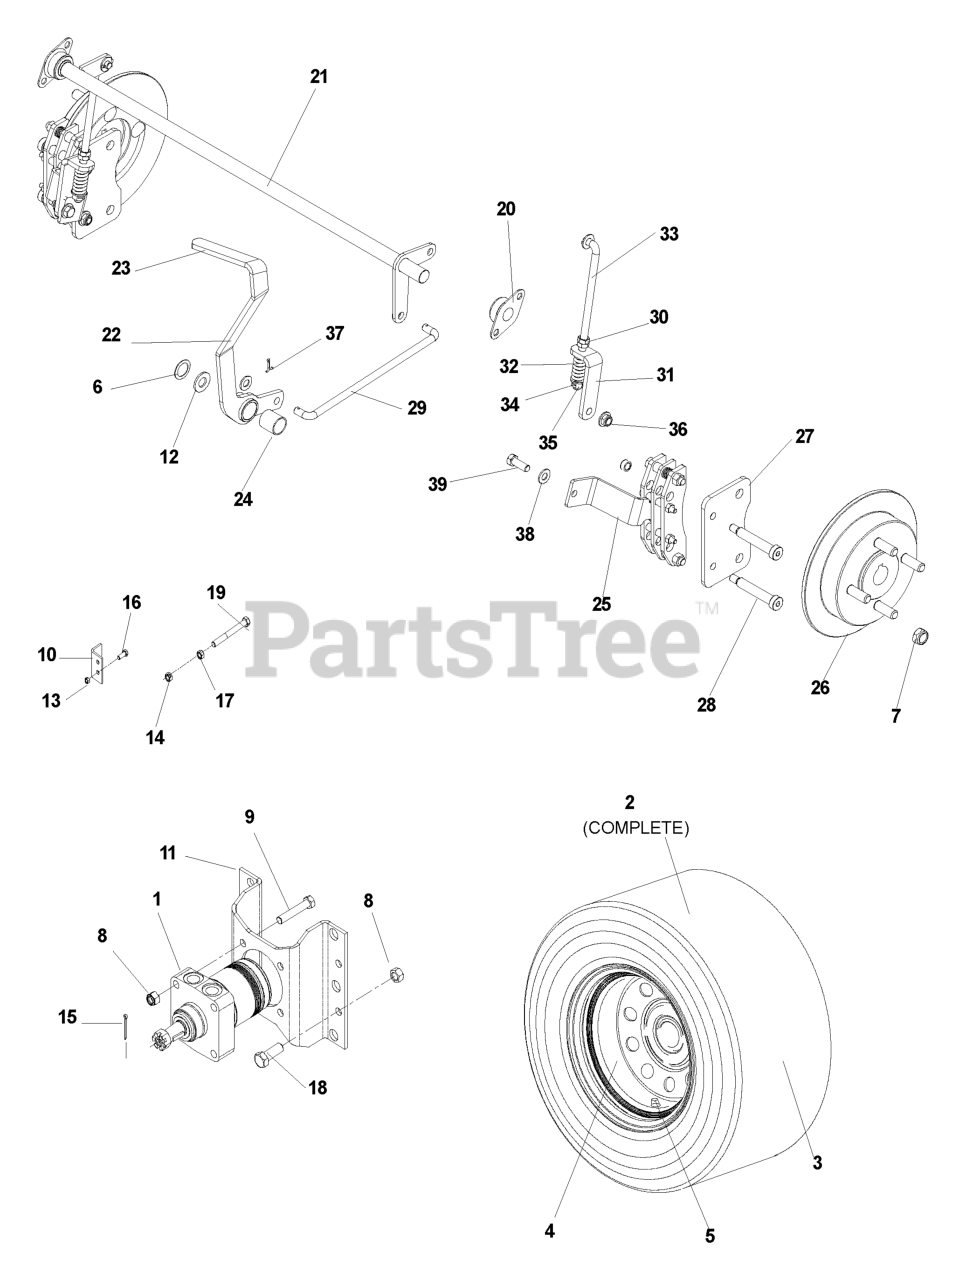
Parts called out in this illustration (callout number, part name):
1	MOTOR, HYDRUALIC
2	TIRE
3	TIRE
5	VALVE STEM
6	RING, RETAINING, EXT, 7/8
7	NUT, 1/2-20, LUG
8	NUT, 1/2-13, NYLOC
9	HCS, 1/2-13 X 2 3/4, GR5
11	MOTOR STANDOFF, TE
13	NUT, 1/4-20, NYLOC
14	NUT, 3/8-16, NYLOC
15	PIN COTTER, 1/8 X 1 1/2
16	HCS, 1/4-20 X 3/4, GR5
17	NUT, 3/8-16, WHIZLK
18	BOLT, 1/2-13 X 1 1/4, WHIZLK, SP
19	HCS, 3/8-16 X 2 1/2, GR5
21	BRAKE CROSS SHAFT
22	BRAKE LEVER
23	GRIP PARK BRAKE
25	CALIPER
27	PLATE, BRAKE
28	SCREW, 3/8-16 X 2 1/2, SKT HD
29	LINKAGE, BRAKE
30	NUT, 3/8-24, JAM
33	LINKAGE, REAR BRAKE
34	WASHER, 3/8, SAE
35	NUT, 3/8-24, CENTERLOCK, GR5
36	NUT, 3/8-16, THIN NYLOC
37	PIN COTTER, 3/32 X 3/4
38	WASHER, 3/8, SAE
39	HCS, 3/8-16 X GR5
